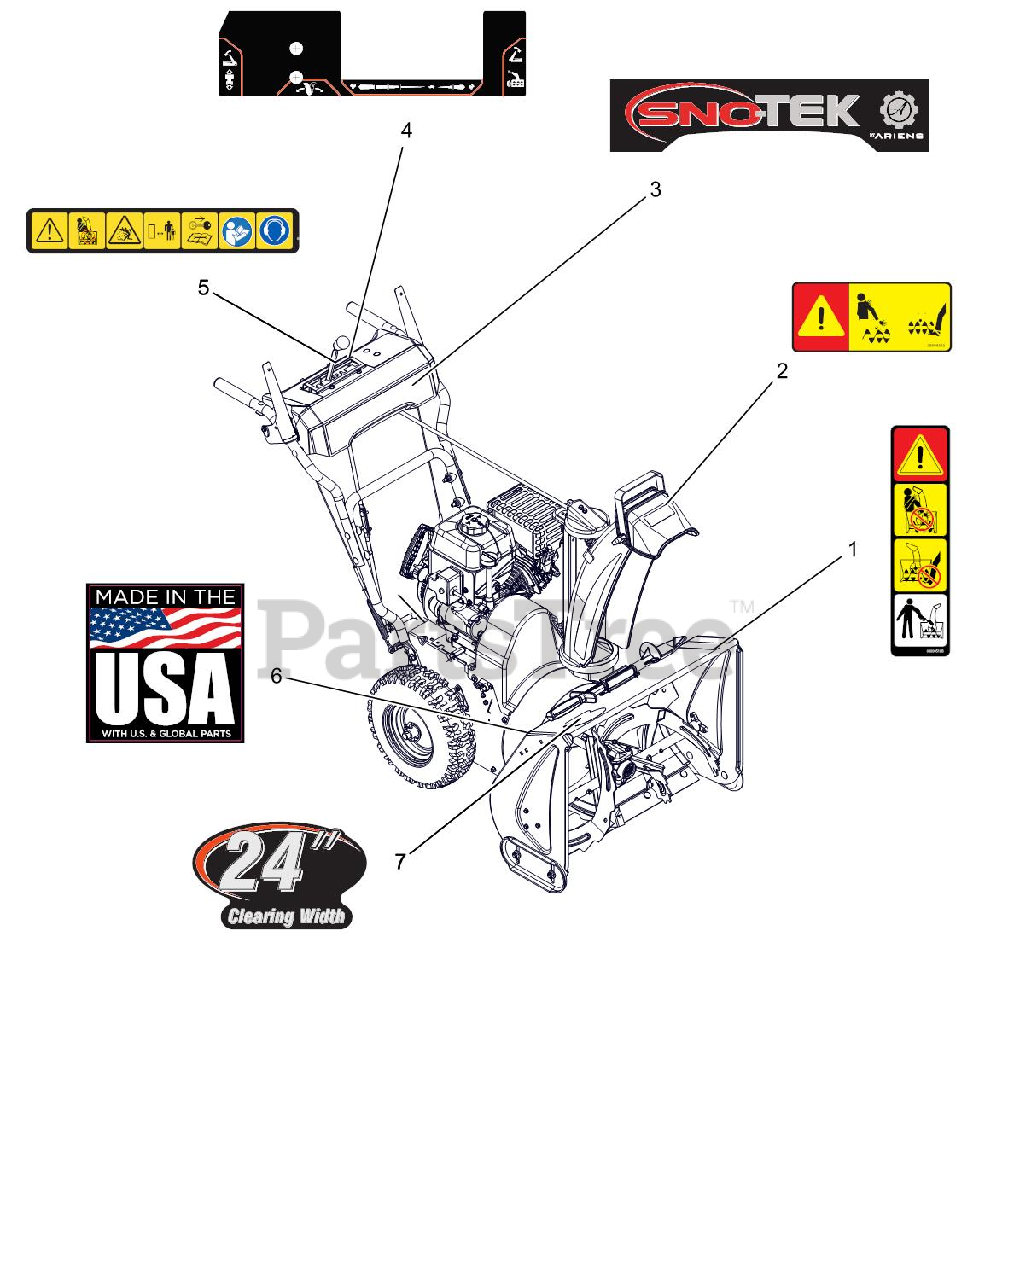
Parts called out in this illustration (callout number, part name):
1	DECAL, DANGER - ROTATING PARTS
2	DECAL, DANGER SNO-TEK
3	DECAL, DASH, SNO-TEK
4	DECAL,CONTROL-COMP MAN
5	DECAL,DASH - SAFETY
6	DECAL, MADE IN USA
7	DECAL, HOUSING SNO-TEK 24
